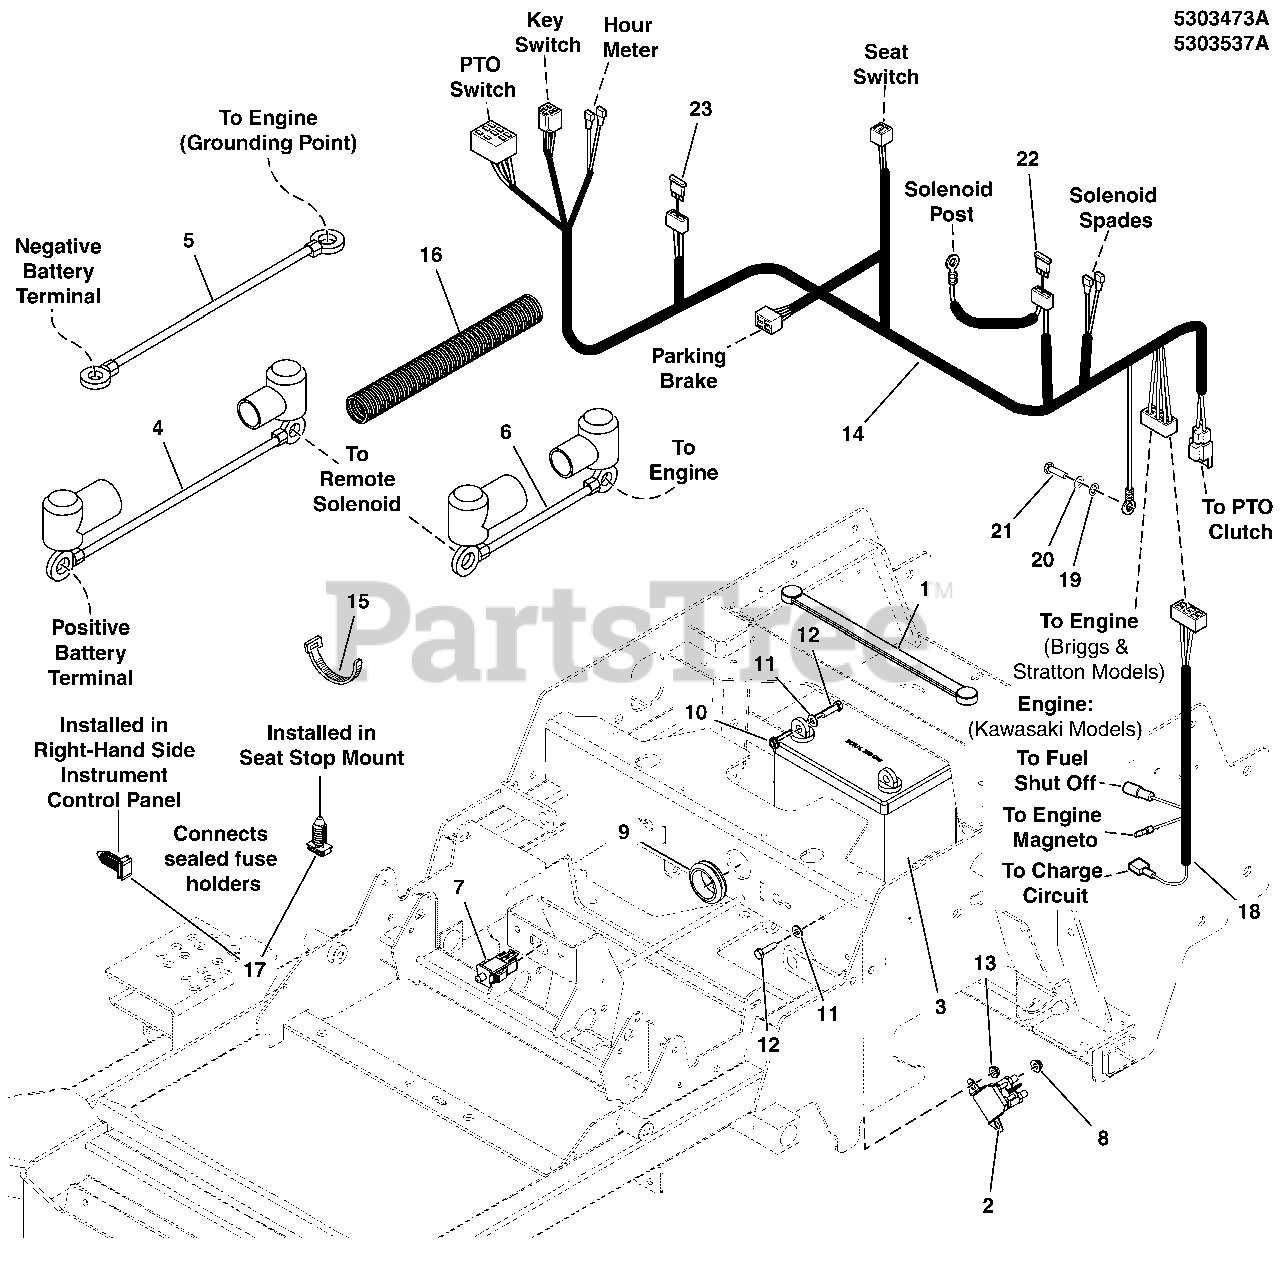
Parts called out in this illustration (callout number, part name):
1	STRAP, Rubber, 13"
2	SOLENOID, 1/4-20 STD, 2 Spade
3	BATTERY, MNTNCE FREE, 300CCA 9 PLTS WET
4	BATTERY CABLE, POS, 22, 1/4-5/16
5	BATTERY CABLE, NEG, 14, 5/16-13/32
6	BATTERY CABLE, POS, 22, 1/4-5/16
7	SWITCH, DP, NO/NC, Snap-In
8	NUT, 1/4-20, Keps, Conical Washer
9	GROMMET, 1-1/2" ID FOR 1/4" METAL
10	NUT, Serrated, Flange, 1/4-20, GR5
11	WASHER, Flat, 1/4
12	CAPSCREW, Hex Head, 1/4-20 x 3/4 (stiffener to top of cover)
13	NUT, Flange Nylock , 1/4-20
14	WIRE HARNESS, MAIN, SM, ZTR
14	HARNESS, SMALL, ZTR WIRING
15	TIE, SELF-LOCKING, 12"
16	WIRE LOOM, 3/8 ID X 18 IN
17	FIR TREE MOUNT, PACKARD
18	WIRE HARNESS, JUMPER, KAWI
19	WASHER, 5/16" Internal Tooth Lock
20	WASHER, Flat, 5/16
21	BOLT, M8-1.25 X 2.MM GD 8.8
22	FUSE, ATO, 20 AMP (SV)
23	FUSE, ATO, 15 AMP (SV)
24	NUT, Hex, Serrated Flange, M8-1.25
